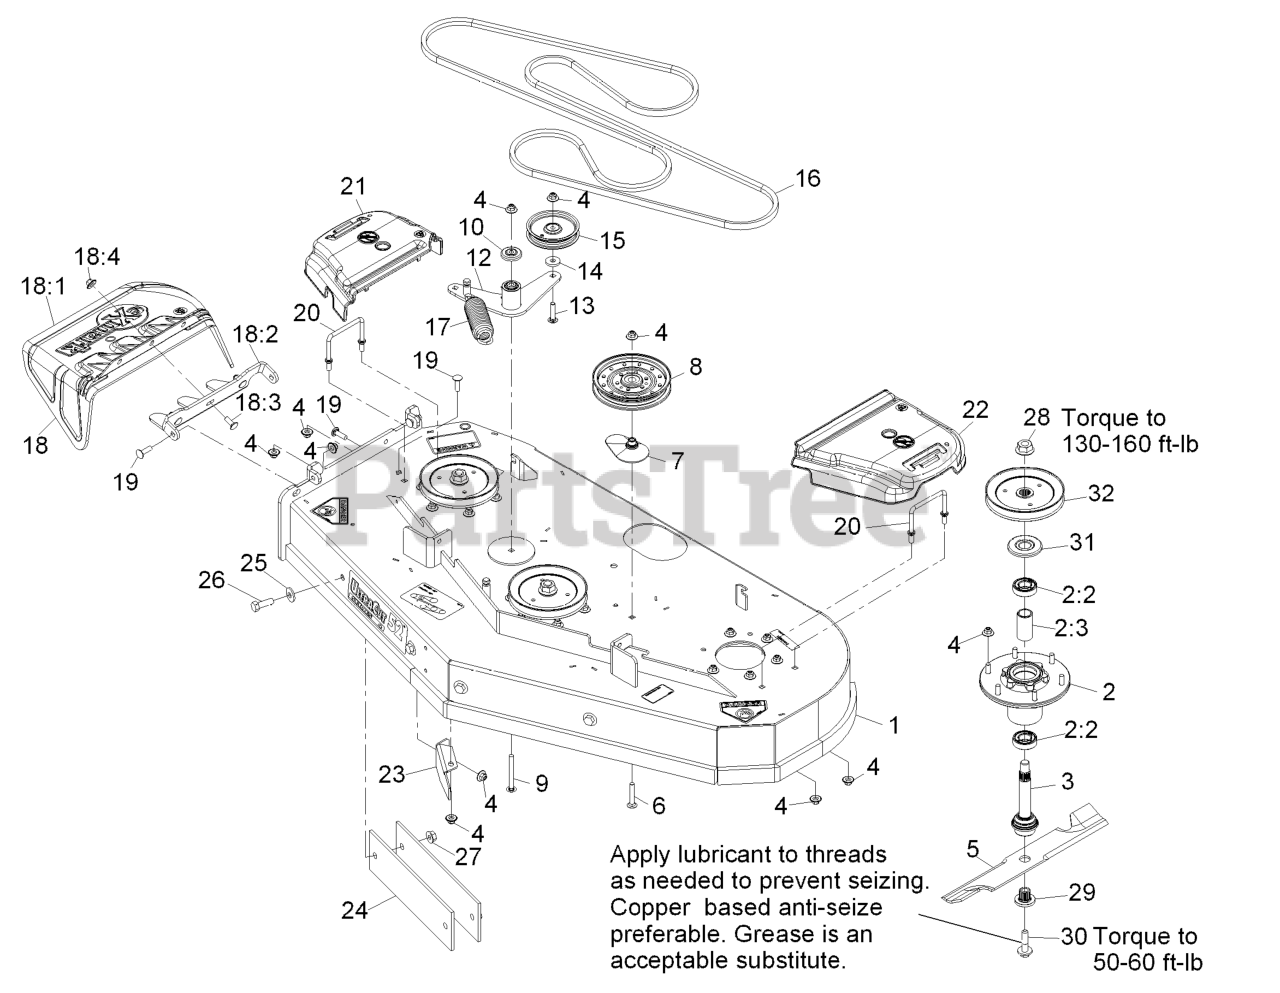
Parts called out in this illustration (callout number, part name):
1	DECK ASM-524
2	ASM-CUTTER HSG WITH BEARINGS
2:2	BEARING-BALL
2:3	SPACER-BEARING
3	ASM-SPINDLE AND SEAL
4	Nut-Nyloc 3/8-16 Flg
6	Bolt-Carriage 3/8-16 X 2 1/4
7	SPACER-PULLEY
9	SCREW-CARR
10	GUARD-TOP
12	IDLER ARM ASM W/BEARINGS
13	SCREW-CARR SPECIAL
15	PULLEY-IDLER
16	BELT-V
18	ASM,DISCHARGE CHUTE
18:1	CHUTE,DISCHARGE
18:2	BRACKET,DISCHARGE CHUTE
18:3	SCREW-CARR
18:4	Nut-Nyloc 3/8-16 Flg
19	Bolt-Carriage 3/8-16 X 1 1/4
20	WIREFORM-COVER
21	COVER-BELT, RH
22	COVER-BELT, LH
23	BAFFLE,DISCHARGE 52/60
24	BAR,WEIGHT
25	WASHER-SPRING
26	SCREW-HH
27	NUT-HHF
28	NUT-FLANGE
29	BUSHING,SPLINED
30	SCREW,SEMS 1/2-20 X 2.19
31	GUARD,BEARING TOP .989
32	SHEAVE,BLADE DRIVE 6.50
